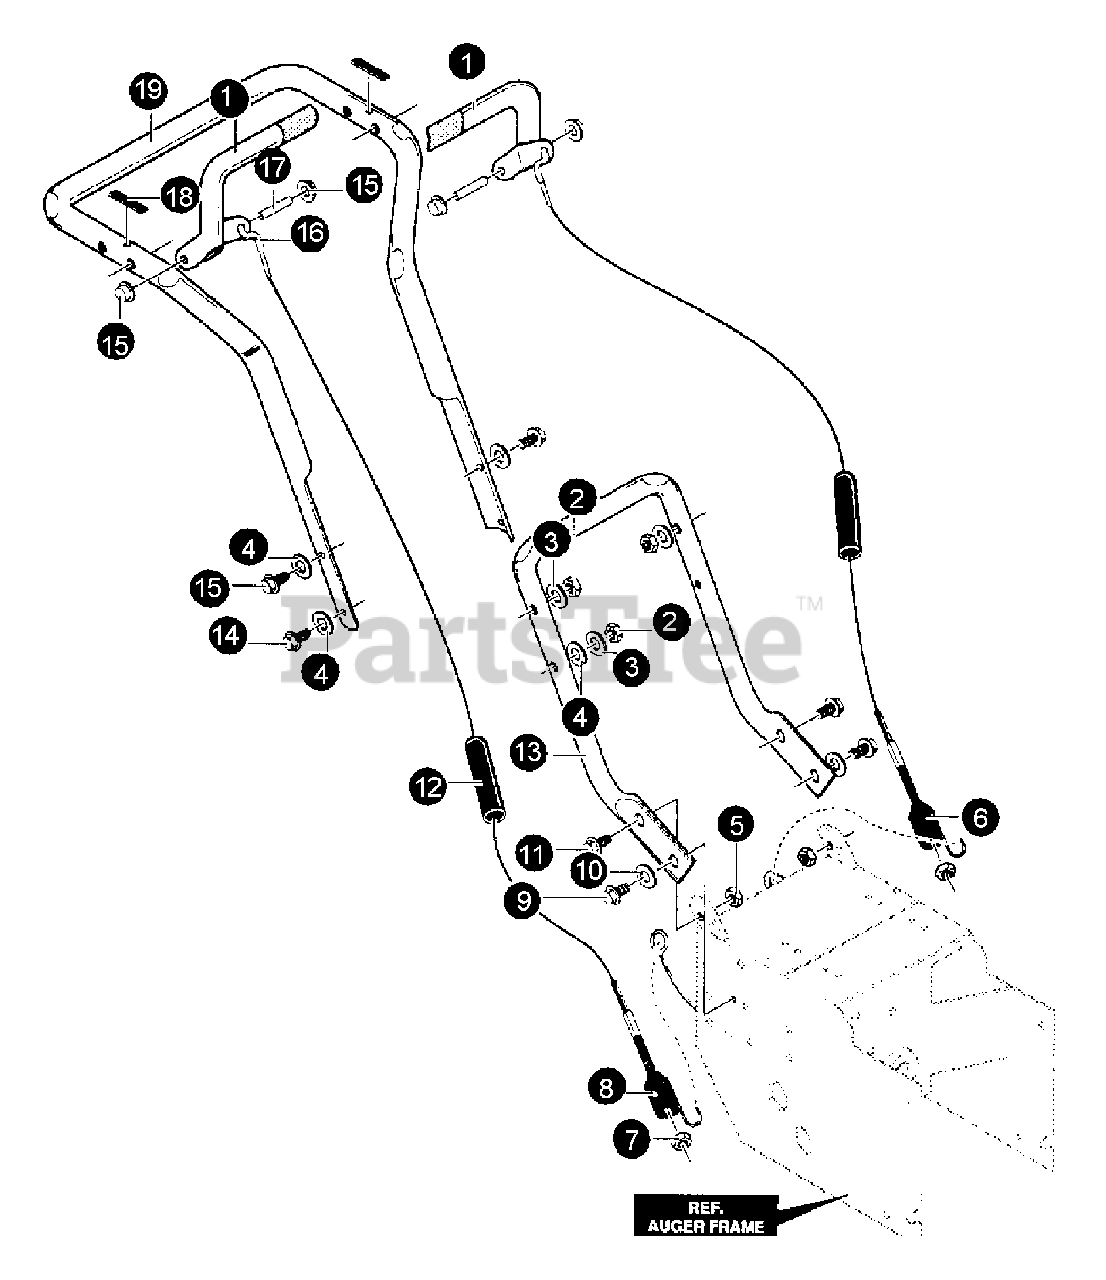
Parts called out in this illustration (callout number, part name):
1	CLUTCH HANDLES SET
2	NUT - 3/8-16
3	LOCKWASHER
4	WASHER
5	NUT - 5/16-18
6	SPRING
7	NUT - 1/4-20
8	SPRING, AUGER CLUTCH
9	SCREW - 5/16-18 X 1/2"
10	LOCKWASHER
11	SCREW - 5/16-18 X 3/4"
12	BOOT, CLUTCH SPRING
13	HANDLE - LOWER
14	SCREW - 3/8-16 X 2"
15	PUSHNUT
16	CABLE, CLUTCH
17	PIN, PIVOT CLUTCH
18	BUMPER, RECT
19	HANDLE - UPPER
